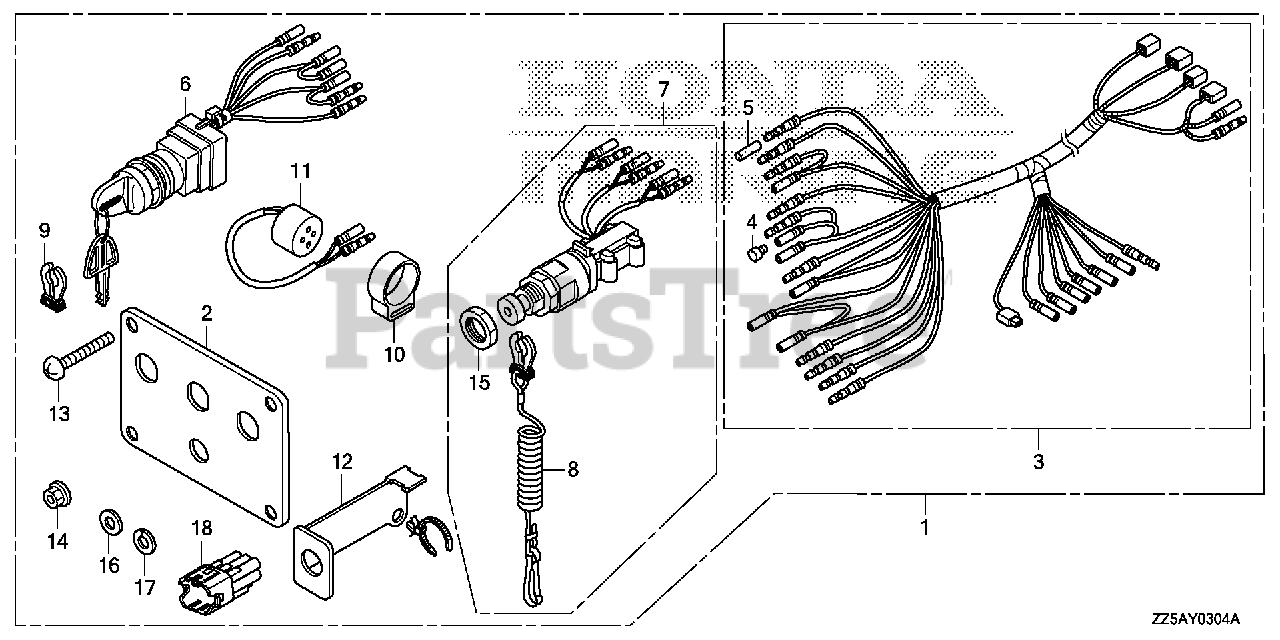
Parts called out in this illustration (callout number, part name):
1	PANEL KIT, SWITCH (TRIPLE)
2	PANEL, CONTROL (TRIPLE)
3	HARNESS ASSY., SWITCH PANEL
4	PLUG, CONNECTOR (INNER)
5	PLUG, CONNECTOR (OUTER)
6	SWITCH ASSY., COMBINATION
7	SWITCH ASSY., EMERGENCY STOP (TRIPLE)
8	WIRE, EMERGENCY
9	CLIP, EMERGENCY LOCK
10	SUSPENSION, AUDIBLE PILOT
11	BUZZER, WARNING
12	BRACKET
13	SCREW, PAN (5X40)
14	NUT, FLANGE (5MM)
15	NUT
16	WASHER, PLAIN (5MM)
17	WASHER, SPRING (5MM)
18	DUMMY, WATERPROOF CONNECTOR (GREEN)
